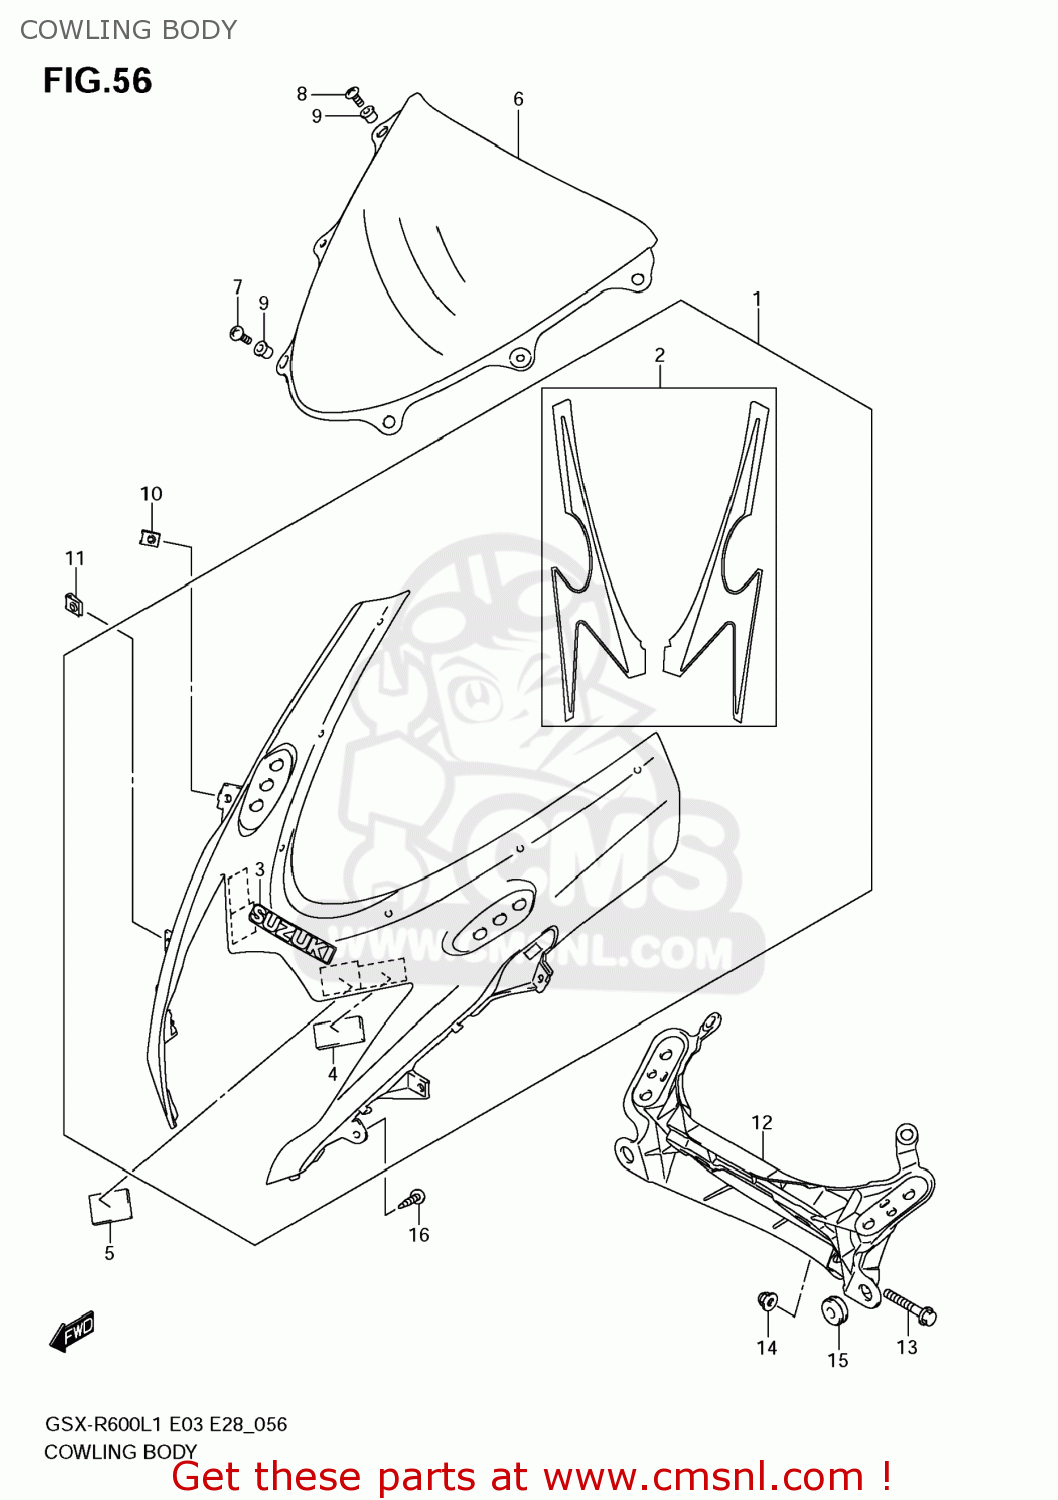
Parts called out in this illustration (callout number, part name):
1	COWLING,BODY(WHITE)
2	TAPE SET,BODY COWL
3	EMBLEM,SUZUKI
4	CUSHION,BODY COWLING
5	FASTENER
6	WINDSCREEN
7	SCREW(5X18)
8	SCREW(5X15)
9	NUT
10	NUT
11	NUT
12	BRACE,COWLING
13	BOLT(8X45)
14	NUT
15	CUSHION
16	SCREW
